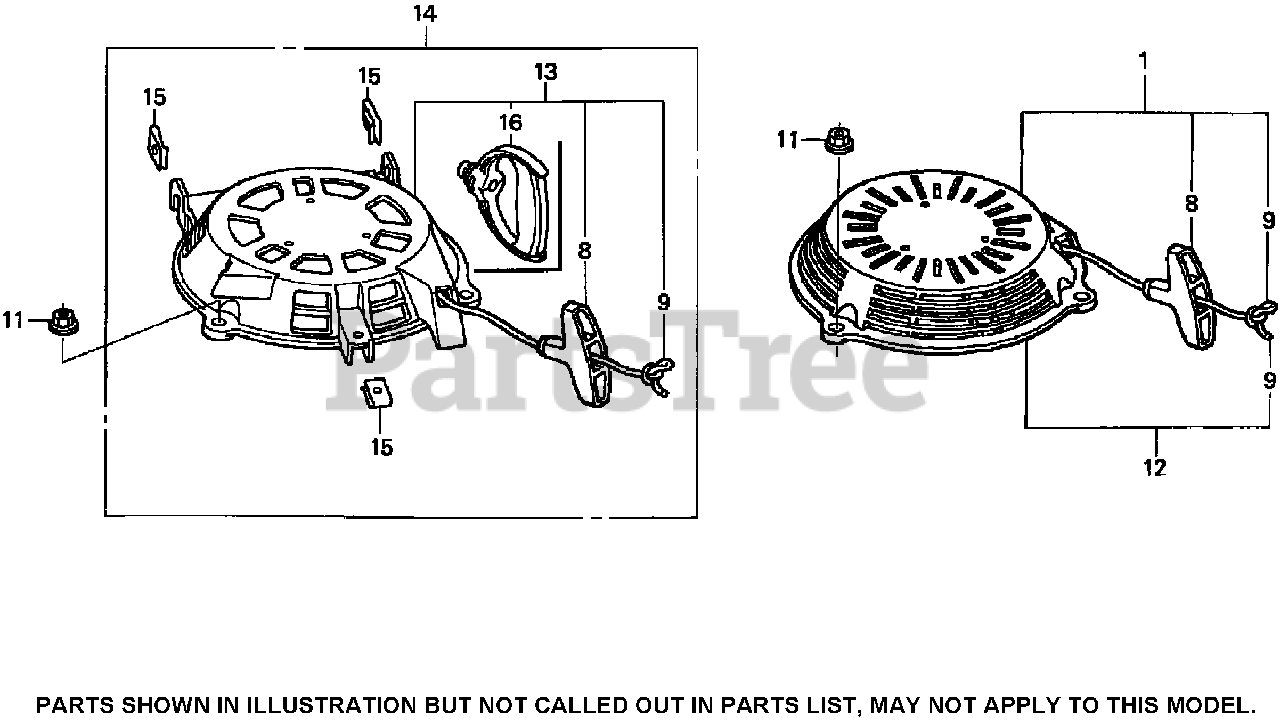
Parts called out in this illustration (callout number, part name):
9	ROPE-STARTER, RECOIL
11	NUT-FLANGE (6MM)
13	STARTER ASM., RECOIL
15	NUT-COWL
16	KNOB-STARTER, RECOIL
